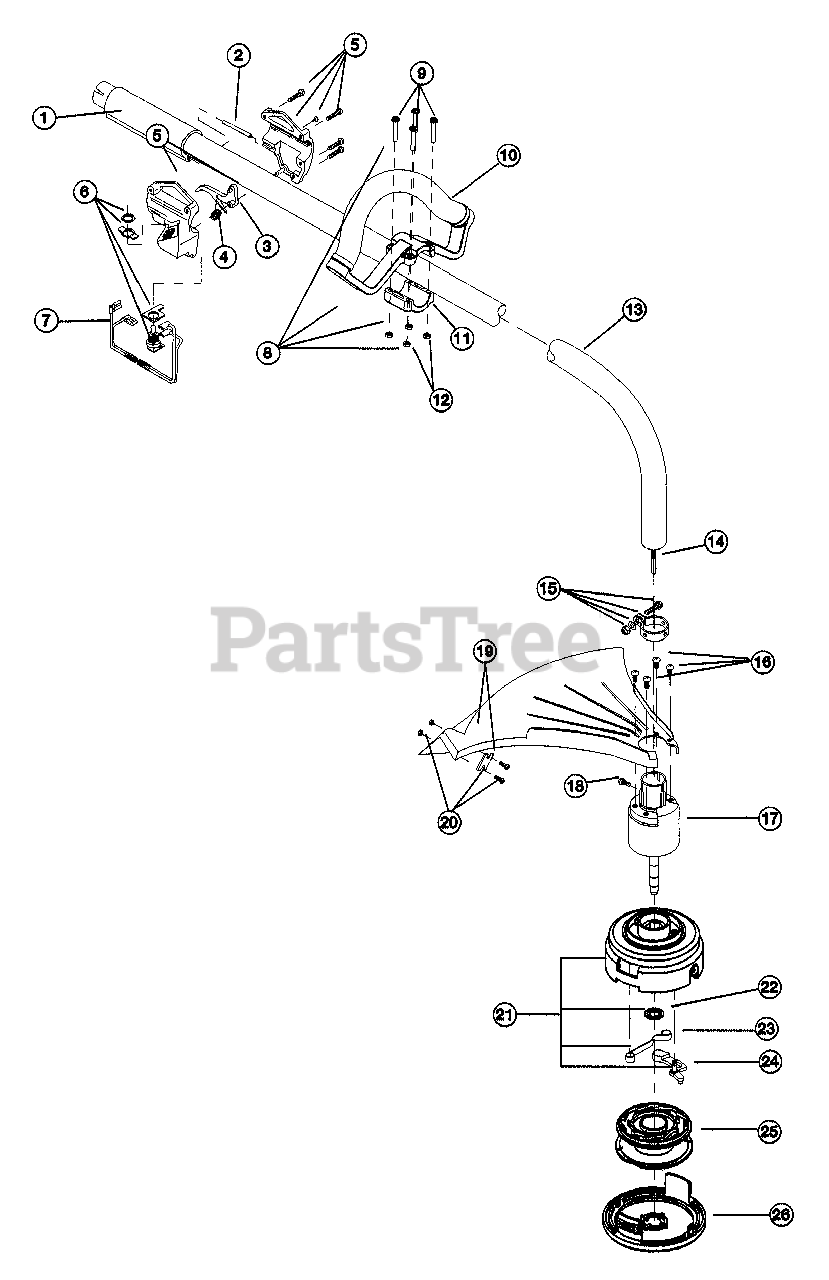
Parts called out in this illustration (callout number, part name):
2	Throttle Cable Assembly
3	Throttle Trigger
4	Throttle Trigger Spring
5	Throttle Trigger Assembly
6	Switch Assembly
7	Wire Lead Assembly
8	Loop Handle Assembly
10	Loop Handle
11	Bottom Clamp
13	Drive Shaft Housing Assembly
14	Flexible Drive Shaft
15	Lower Clamp Assembly
16	Shield Mounting Screw
17	Bushing Housing Assembly
18	Anti-Rotation Screw
19	Shield and Blade Assembly
20	Blade Assembly
21	Outer Spool w/ Retainer
22	Retainer
23	Pawl Spring
24	Ratchet Pawl
26	Spool Cover
